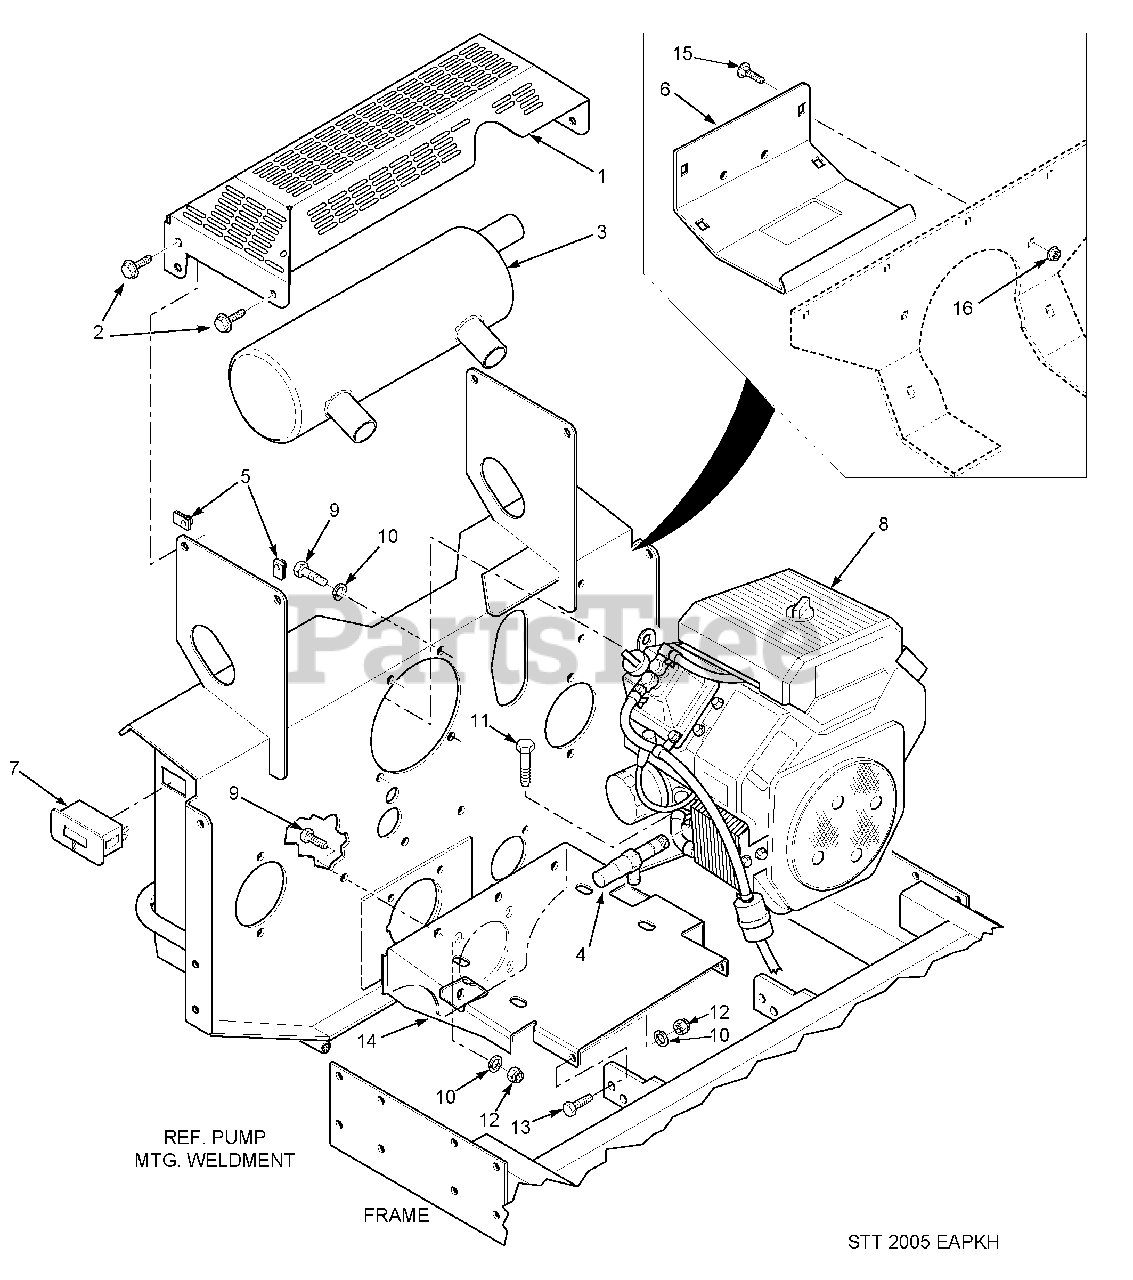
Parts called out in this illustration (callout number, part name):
1	Muffler Guard
2	Screw, Hex Serrated Flange 1/4-20 x 3/4"
3	Muffler, Part Of Engine
4	Oil Drain Extension
5	U-Nut, 1/4-20
6	Rear Cover
7	Hour Meter
8	Engine, Kohler 27 CH
9	Bolt, Hex Head 3/8-16 x 1"
10	Lockwasher, 3/8" Spring
11	Bolt, Hex Head 3/8-16 x 1-3/4"
12	Nut, Hex Elastic Stop 3/8-16
13	Bolt, Hex Head 3/8-16 x 1-1/4"
14	Plate, Engine Mounting
15	Bolt, Carriage 5/16-18 x 3/4"
16	Nut, Hex Serrated Flange 5/16-18
